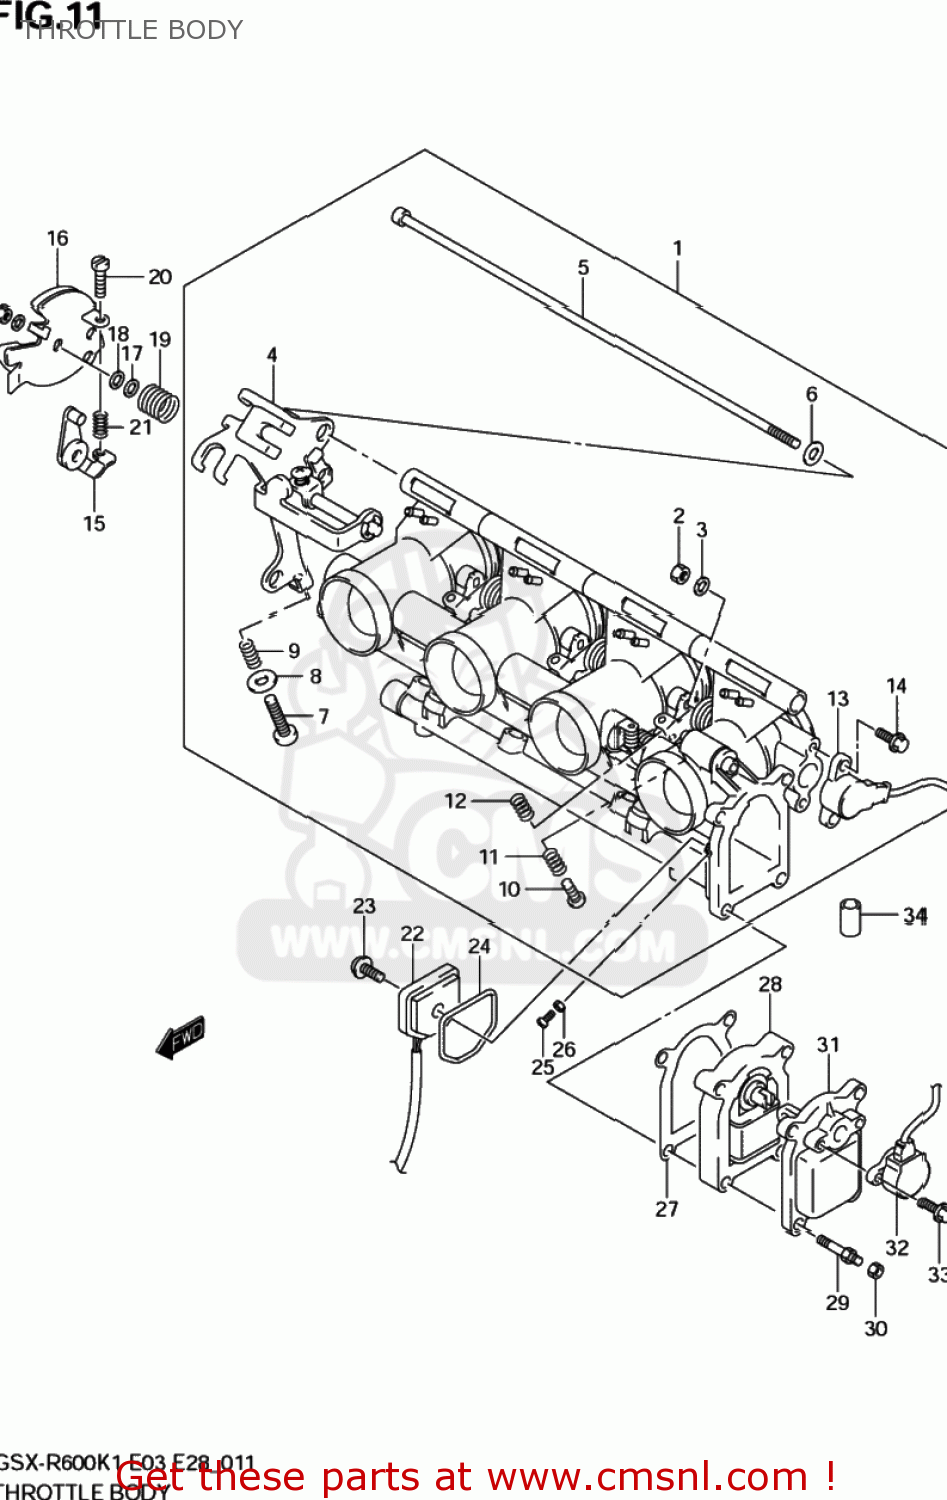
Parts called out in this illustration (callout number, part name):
1	BODY ASSY,THROTTLE
2	NUT
3	LOCK WASHER
4	BRACKET ASSY
5	BOLT
6	WASHER
7	SCREW,ADJUST
8	WASHER
9	SPRING
10	SCREW
11	SPRING
12	SPRING,THROTTLE SCREW
13	SENSOR ASSY
14	SCREW
15	LEVER
16	THROTTLE LEVER ASSY
17	WASHER
18	WASHER
19	SPRING
20	SCREW
21	SCREW SET,ADJUST
22	HARNESS ASSY
23	SCREW
24	SEAL
25	SCREW
26	NUT
27	GASKET (NAS)
28	YOKE ASSY
29	BOLT
30	NUT
31	COVER ASSY
32	SENSOR ASSY
33	SCREW
34	HOSE
